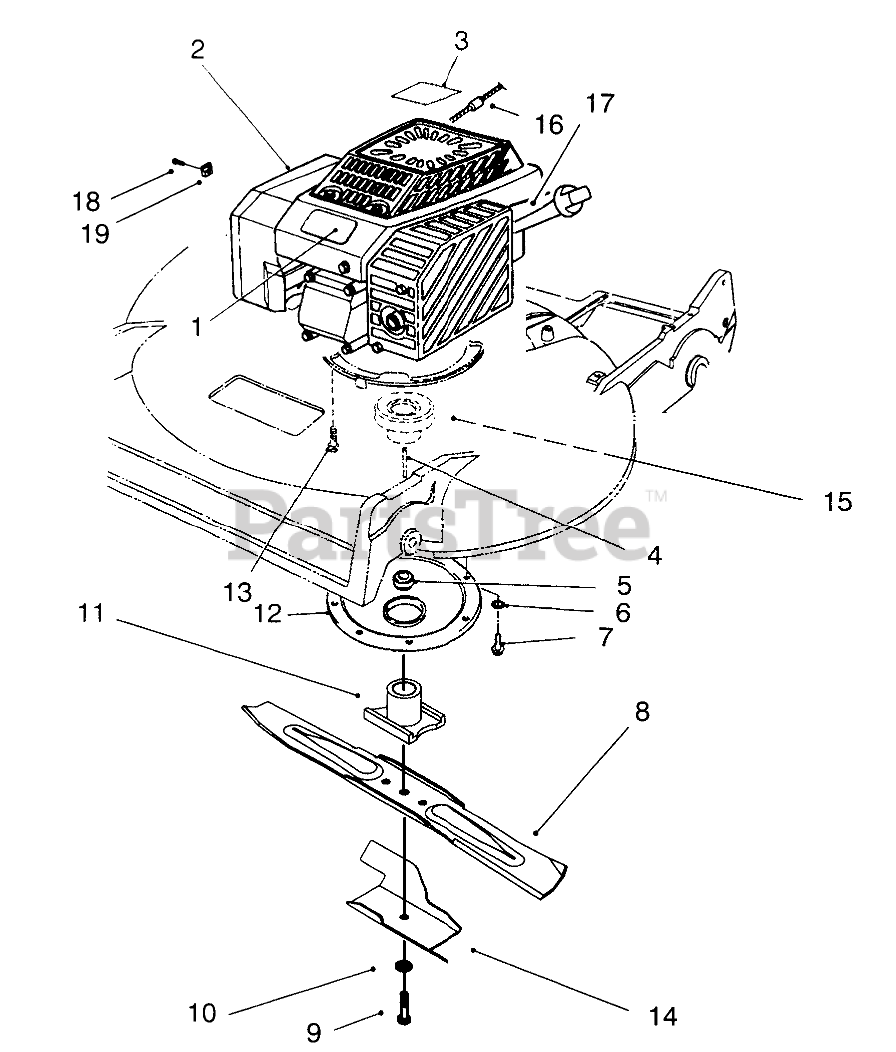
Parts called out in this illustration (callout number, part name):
1	DECAL - PROLINE
2	Engine-Complete
3	DECAL - ENGINE
4	KEY-SQUARE
5	SPACER-BLADE RETAINER
6	WASHER-LOCK, INTERNAL
7	SCREW-HWHTF
8	Blade
9	SCREW-BLADE
10	WASHER-LOCK
11	RETAINER-BLADE
12	PROTECTOR-CRANKSHAFT
13	SCREW-HWH
14	Accelerator
15	PULLEY-DRIVER
16	STOP-ROPE
17	COVER - BRAKE F/W
18	CLAMP SCREW F/W ENGINE
19	CLAMP-CASING
